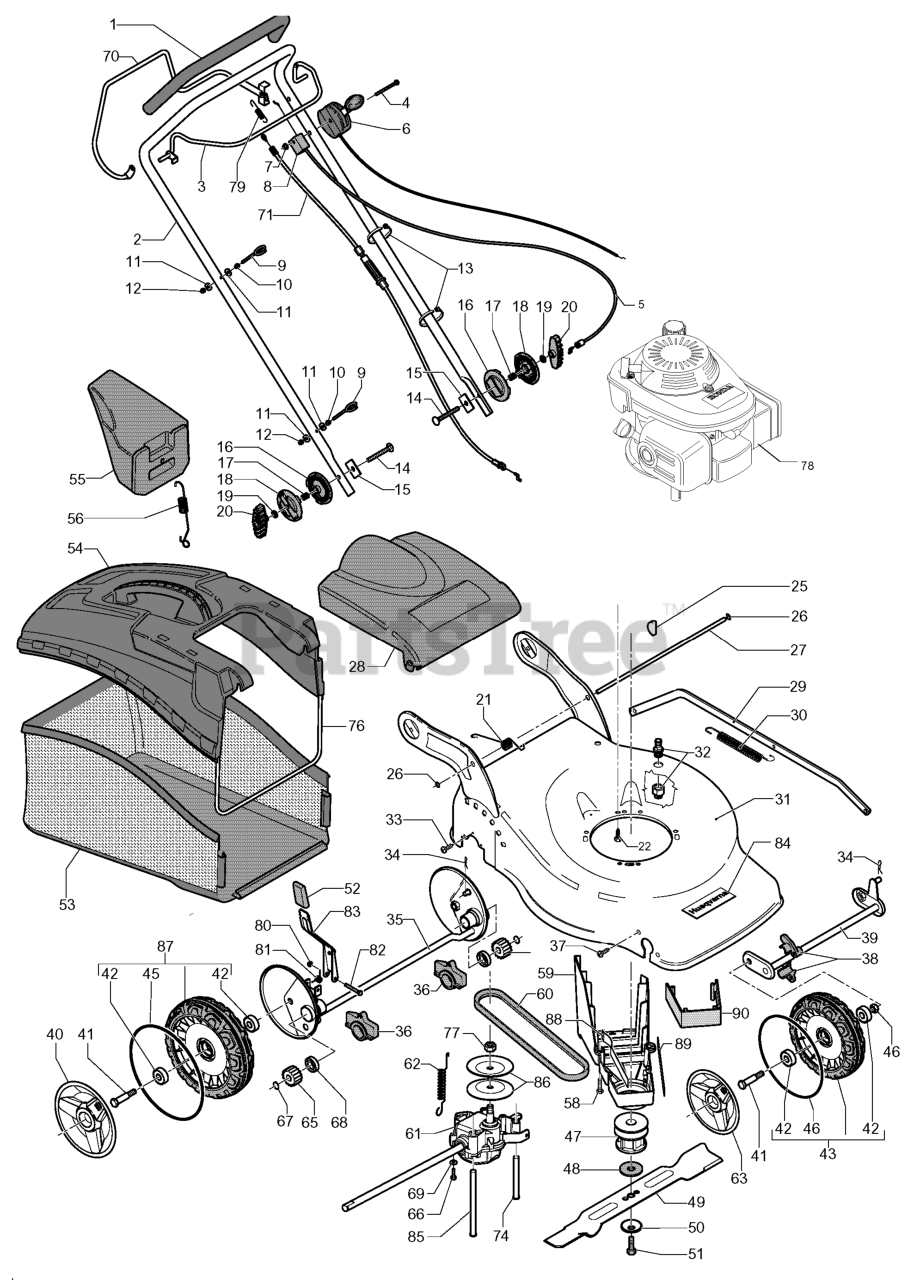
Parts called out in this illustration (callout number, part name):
5	BRAKE WIRE
35	REAR AXLE REAR AXLE WELDED FOR
83	LIFTING LEVER ASSY FOR REAR AX
